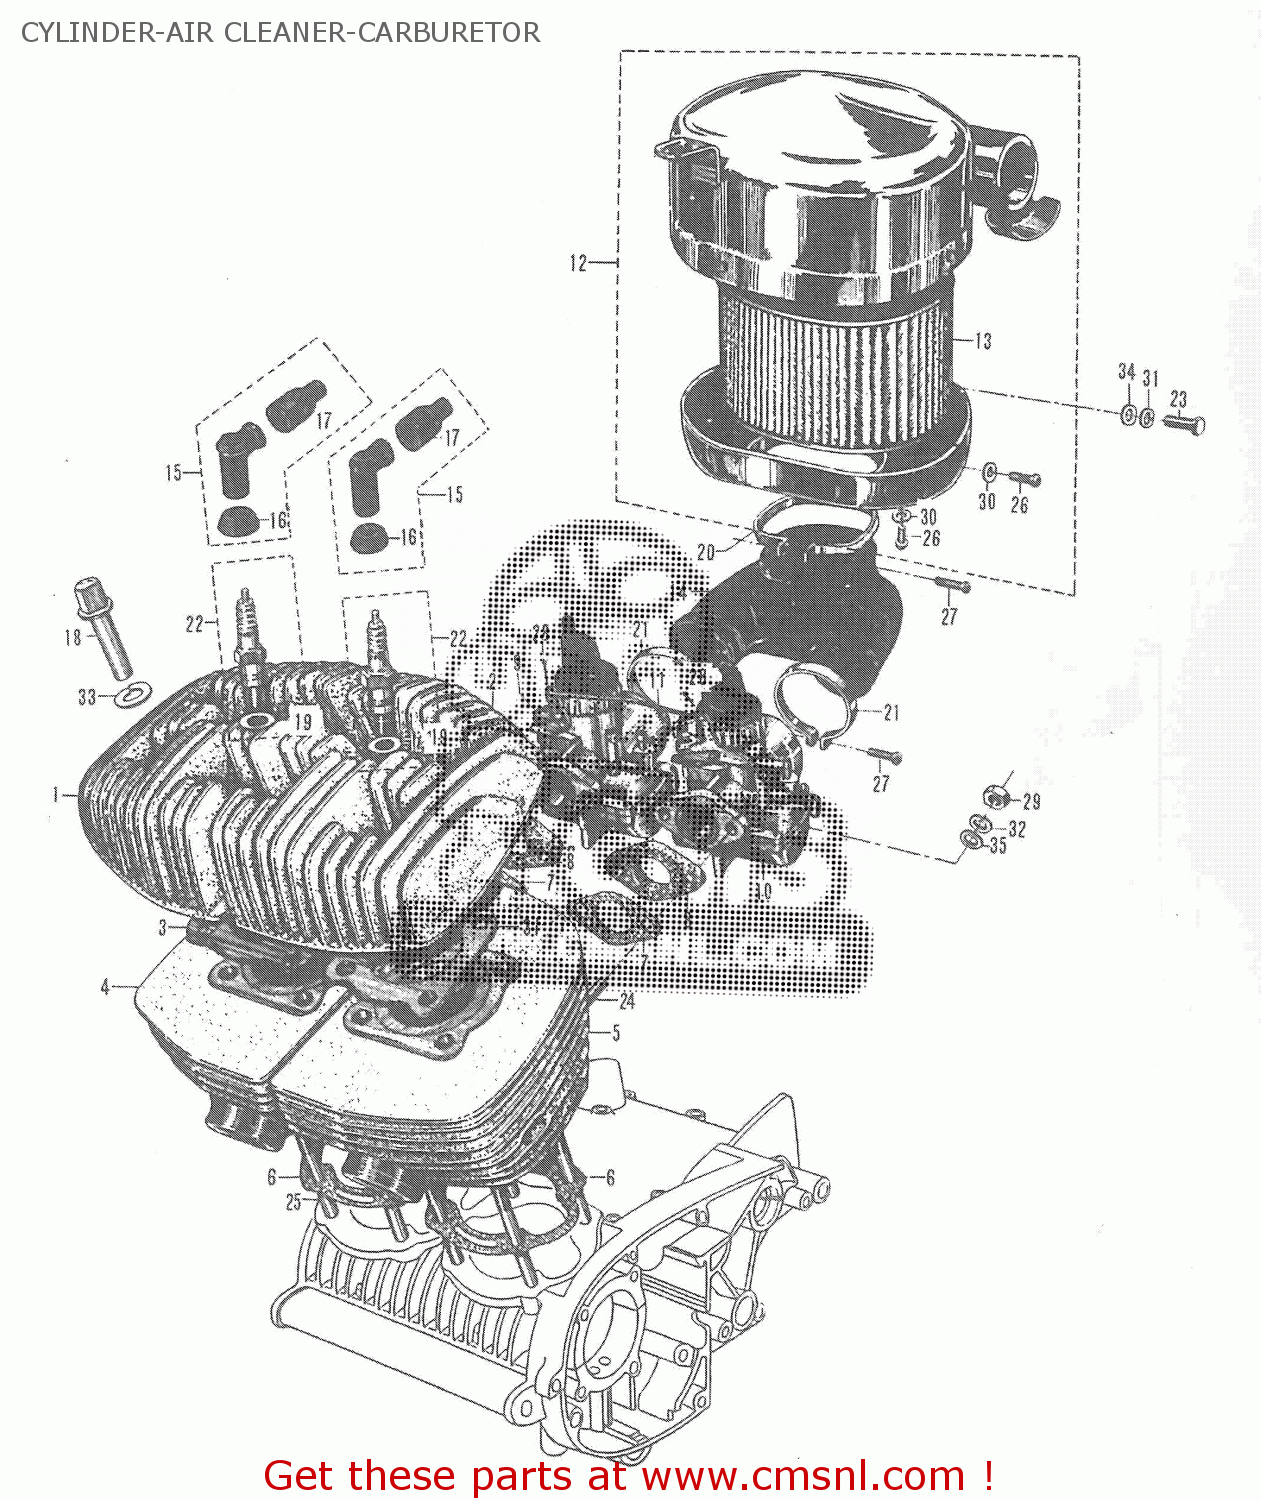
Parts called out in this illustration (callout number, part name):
1	RIGHT CYLINDER HEAD
2	LEFT CYLINDER HEAD
3	GASKET,CYLINDER HEAD (NAS)
4	RIGHT CYLINDER
5	LEFT CYLINDER
6	GASKET,CYLINDE (MCA)
7	GASKET,CARBURETOR (MCA)
8	GASKET,CARBURETOR INSULATOR (NAS)
9	RIGHT CARBURETOR ASS'Y
10	LEFT CARBURETOR ASS'Y
11	PLUNGER LEVER LINK
12	AIR CLEANER ASS'Y
13	AIR CLEANER ELEMENT
14	TUBE,AIR CLEANER OUTLET
15	CAP,SPARK PLUG
16	SEAL,SPARK PLUG
17	SEAL,HIGH TENSION CORD
18	NUT (8MM)
19	GASKET(14X19.2X2) (NAS)
20	AIR CLEANER TUBE REAR CLAMP
21	AIR CLEANER TUBE FRONT CLAMP
22	SPARK PLUG
23	HEXAGON BOLT
24	STUD BOLT
25	STUD BOLT
26	CROSS HEAD SCREW
27	CROSS HEAD SCREW
28	COTTER PIN
29	SMALL HEXAGON NUT
30	LOCK WASHER
31	LOCK WASHER
32	LOCK WASHER
33	LOCK WASHER
34	SMALL FLAT WASHER
35	SMALL FLAT WASHER
